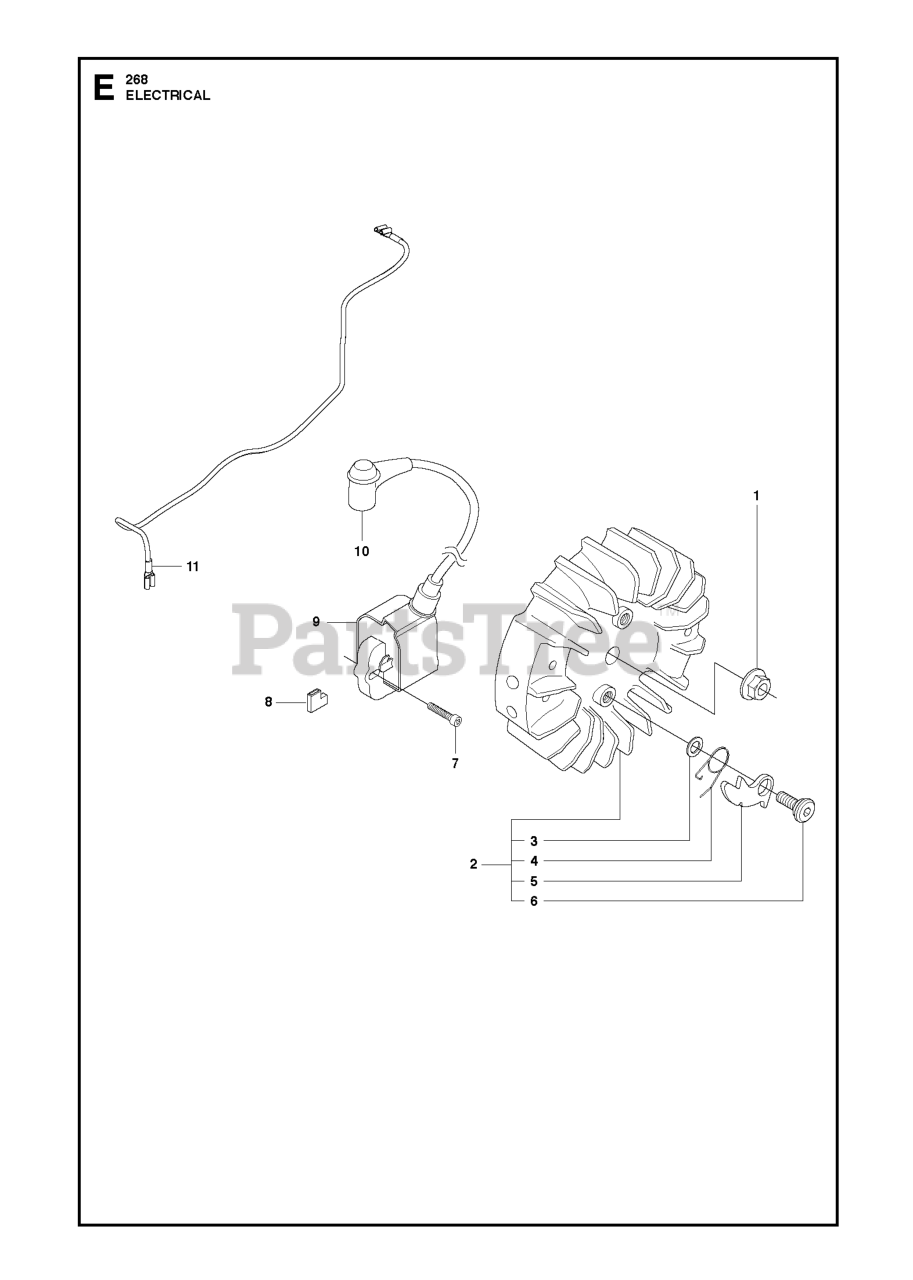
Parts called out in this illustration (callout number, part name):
1	NUT W/ WASHER
6	SCREW M5X14
8	INSULATING CAP
9	IGNITION MODULE
10	SPARK PLUG CONN. KIT
11	SHORTING LEAD
